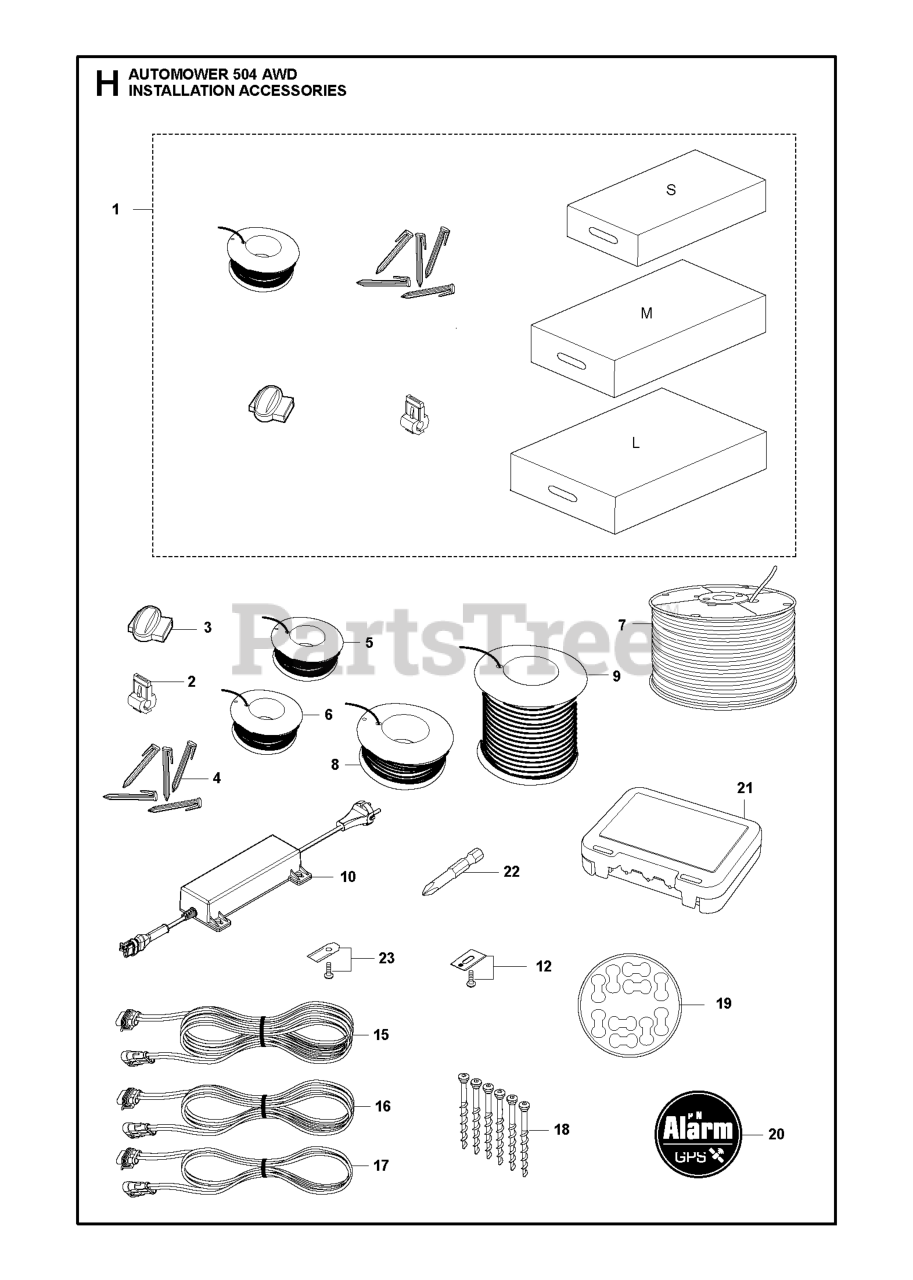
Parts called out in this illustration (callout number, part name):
1	MED AUTOMOWER INSTALL KIT
1	SMALL AUTOMOWER INSTALL KIT
1	LARGE AUTOMOWER INSTALL KIT
2	CONNECTOR 5 PCS, BLISTER
2	BRAKER
2	CONNECTOR 100 PCS
3	SPLICE KIT
3	COUPLER SPLICER, 5 PCS,
3	COUPLER SPLICER, 100 PCS
4	STAPLE 100 PCS, BLISTER
4	STAPLE 100 PCS
5	WIRE 50M STANDARD Ø2.7MM,BLIST
5	WIRE BOUNDARY 150M
5	WIRE 150M, BLISTER
6	WIRE 250M
8	WIRE 500M
9	WIRE (800M)
10	Power Unit
15	CABLE LOW VOLTAGE CABLE P2 5-7
16	CABLE LOW VOLTAGE CABLE P2 5-7
17	CABLE LOW VOLTAGE CABLE P2 5-7
18	SCREW KIT CS
18	SCREW 3 PCS, BLISTER PACK
19	STICKER CABLE MARKERS KIT 10PC
20	Decals
21	CONNECTOR PROTECTION BOX
22	WRENCH BITS CHANGING ROBOTIC B
23	HUS BLADE SET 45 PCS
23	HUS BLADE SET 9 PCS
23	HUS BLADE SET 300 PCS
